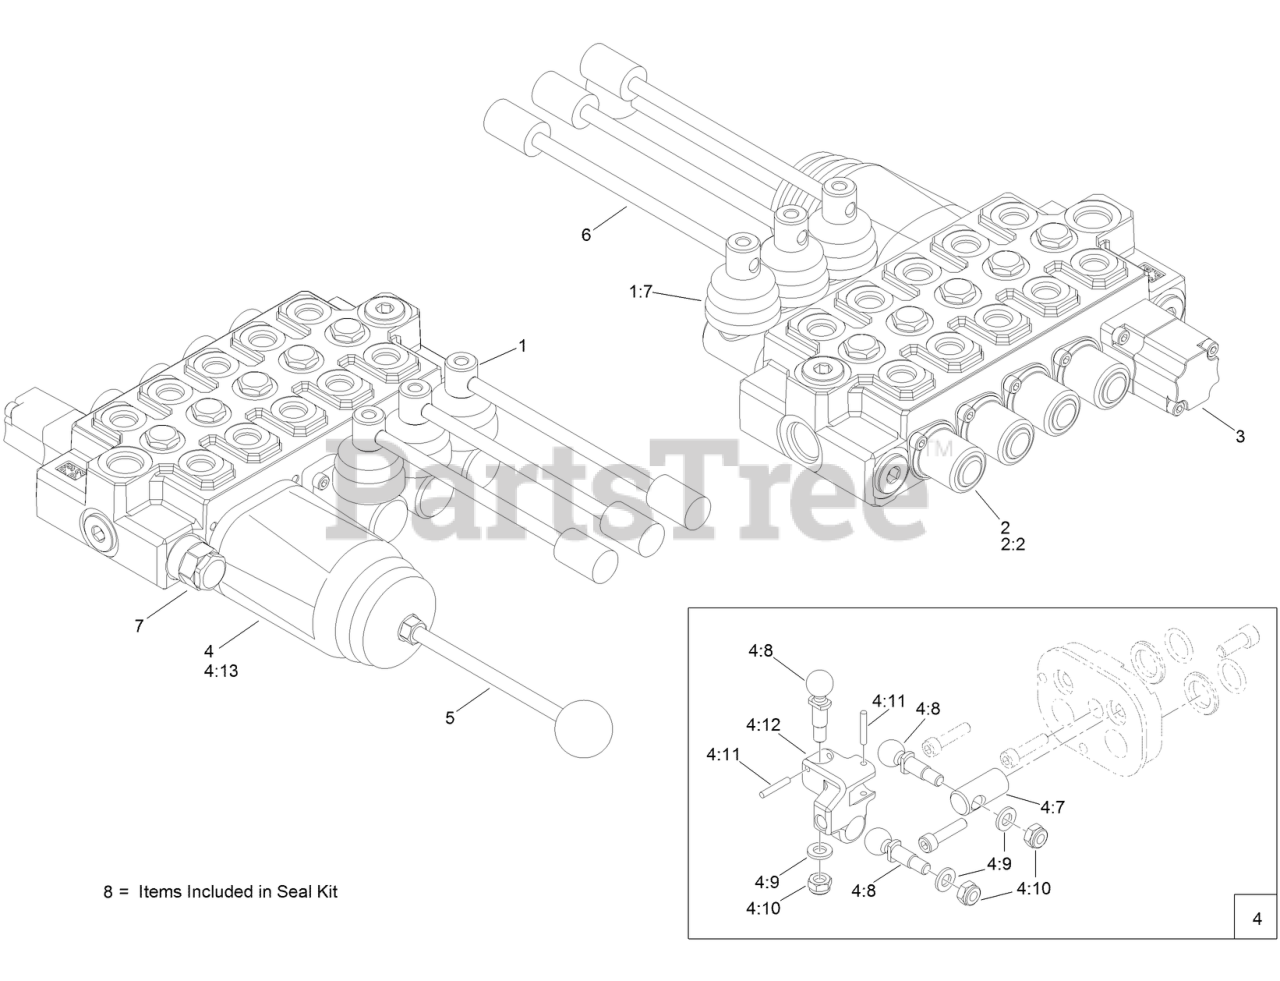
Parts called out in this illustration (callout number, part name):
1	SPOOL-CONTROL
1:7	BOOT-RUBBER
2	SPOOL-CONTROL
2:2	CAP-SPOOL, CONTROL
3	SPOOL-CONTROL
4	JOYSTICK-MECHANISM, RH
4:7	PIN-FOUNDATION, JOINT
4:8	BALL-JOYSTICK
4:9	WASHER-PLAIN
4:10	NUT-LOCK
4:11	PIN-ROLL
4:12	JOINT-JOYSTICK, RH
4:13	BOOT-JOYSTICK
5	LEVER-LONG
6	LEVER-SHORT
7	VALVE-RELIEF
8	SEAL KIT
